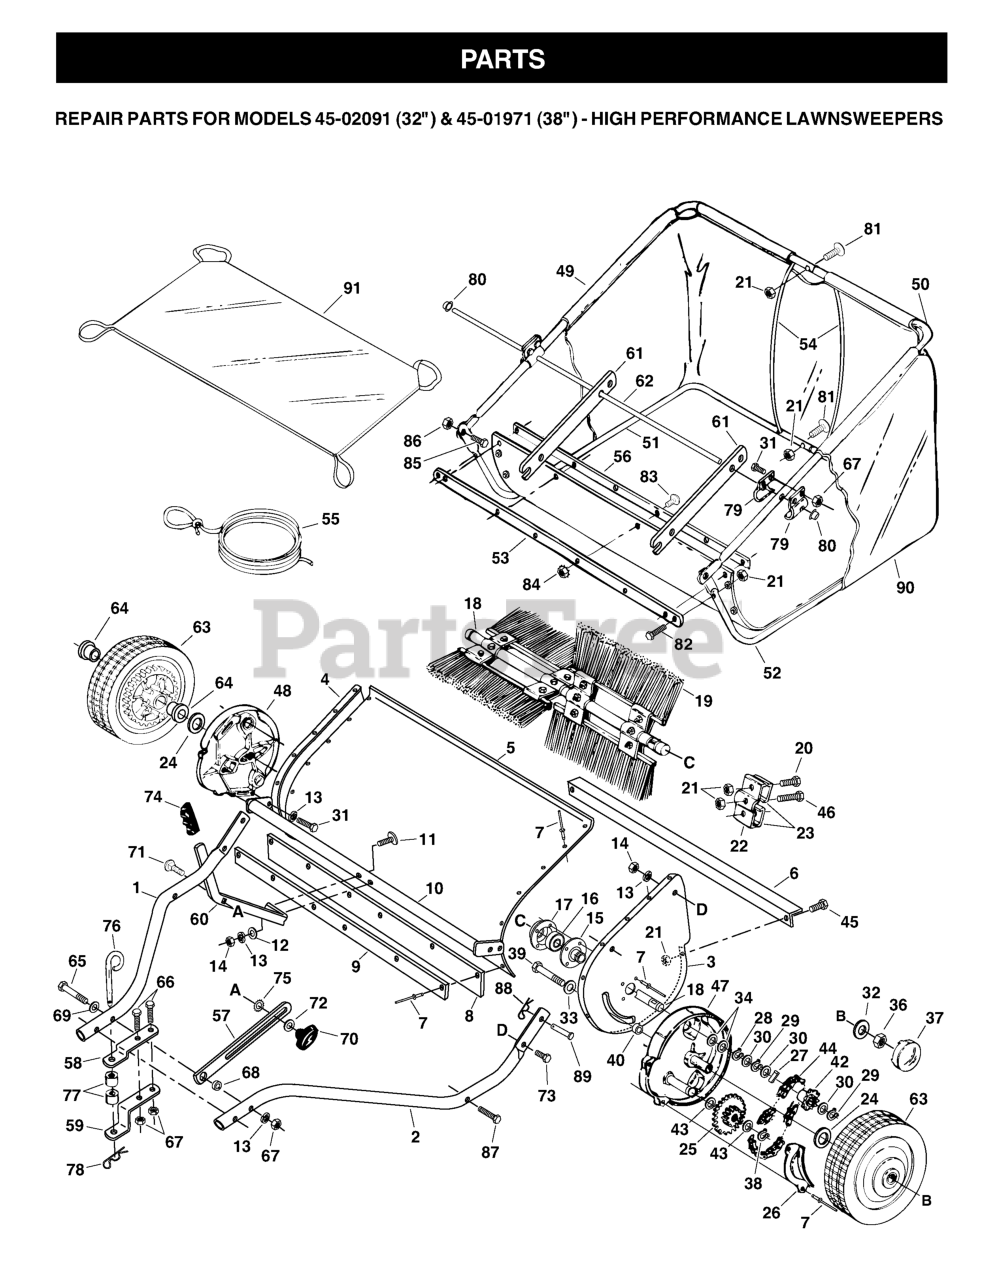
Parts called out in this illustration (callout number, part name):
3	PLATE, L.H.
4	PLATE, R.H.
7	RIVET
11	Bolt, Cv. Hd. 5/16-18 x 1-5/8" Lg.
15	BRUSH BUSHING ASSY
16	BALL BEARING
17	BEARING RETAINER
20	SCREW M6S 6X20
22	BRUSHRETAINER DOUBLE
23	BRUSH RETAINER SINGLE
24	Washer, Flat 1-1/8" x .78" x .025"
25	GEAR SPRUCKET SUB ASSY
26	Dust Cover
28	Ring, Retaining 3/4"
29	Retaining Ring .594" I.D.
30	SHIM WASHER
31	BOLT.FIN.HEX.5/16-18X3/4
32	Washer, Flat 1-1/2" x .375" x .062"
33	WASHER
34	FL-WASHER
36	HEX LOCK NUT 3/8-24THD
38	RETAINING RING 1/2Ä
39	HEX BOLT
40	Spacer 13/32" x 5/8" x 3/16"
42	RATCHET SPROCKET
43	Washer, 1/2" x 1" x .02"
44	ROLLERCHAIN 3/8X1/2"
45	Bolt, Hex 1/4-20 x 1/2" Lg.
48	Housing, Wheel Drive Ass'y. R.H.
54	HOPPER SUPPORT ROD
58	Bracket, Hitch
59	HITCH BRACKET
60	Handle, Height Adjustment
63	WHEEL
64	WHEEL BEARING
65	Bolt, Hex 5/16-18 x 3" Lg.
69	WASHER - M6
70	Knob, Wing 5/16-18 Thread
71	RP BOLT 5/16-18 X3/4 ZN/YEL GR
72	WASHER BRB 8.4X17
74	Rubber Grip
75	WASHER, TOOTH LOCK
76	Pin, Hitch
77	Hitch Adjustment Tube
79	HOPPER MOUNTING CLAMPS
81	Curved Head Bolt 1/4-20 x 1"
82	SCREW M6S 6X30
83	Slotted Truss Head Screw #10-32 x 5/8"
84	LOCKNUT M5
85	HEX BOLT
87	SCREW
90	REPL BY 531 00 28-55
91	REPL BY 531 00 28-56
